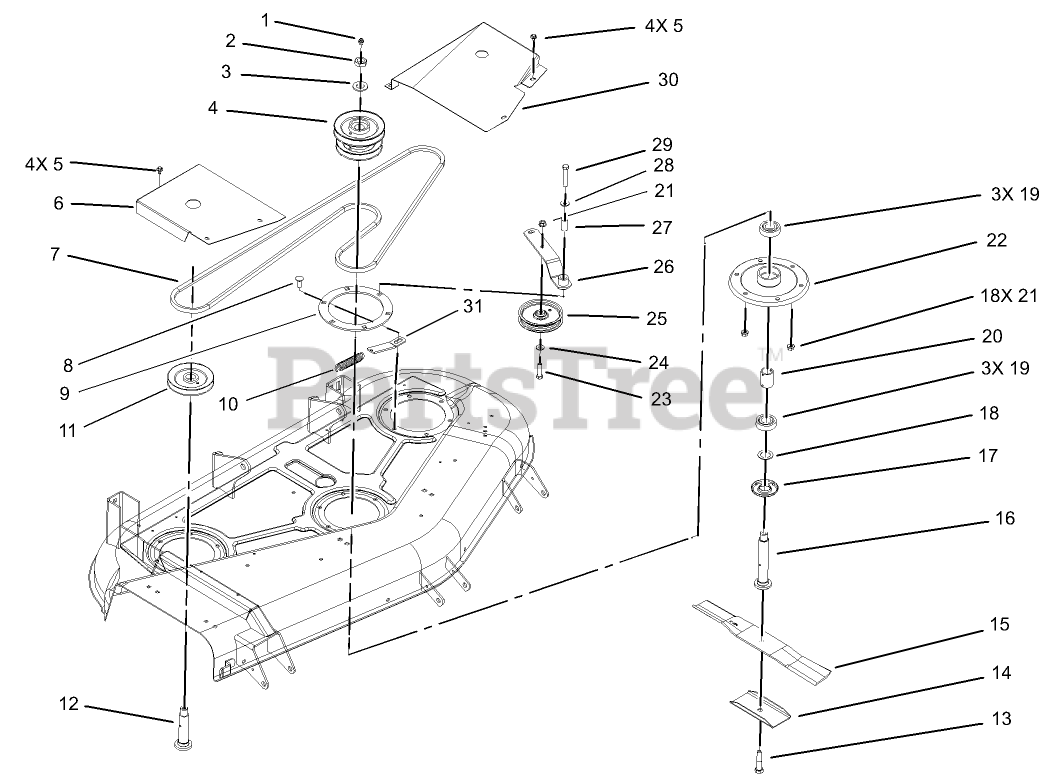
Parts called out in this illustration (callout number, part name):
1	FITTING-GREASE
2	NUT-JAM
3	WASHER-FLAT
4	PULLEY-DOUBLE
5	SCREW-HHFTF
6	COVER-BELT, RH
7	V-BELT
8	SCREW-CARR
9	RING-DECK SUPPORT
10	SPRING-EXTENSION
11	PULLEY
12	SHAFT-SPINDLE
13	SCREW-BLADE
14	STIFFENER-BLADE
16	SHAFT-SPINDLE
17	SHIELD-BEARING
18	WASHER-WHEEL
19	BEARING-BALL
20	SPACER-BEARING
21	NUT-HF
23	SCREW-HH
24	WASHER-FLAT
25	PULLEY-IDLER
26	IDLER ARM ASM
27	SLEEVE
28	WASHER-FLAT
29	SCREW-HH
30	COVER ASM-LH
31	PLATE-SPRING
